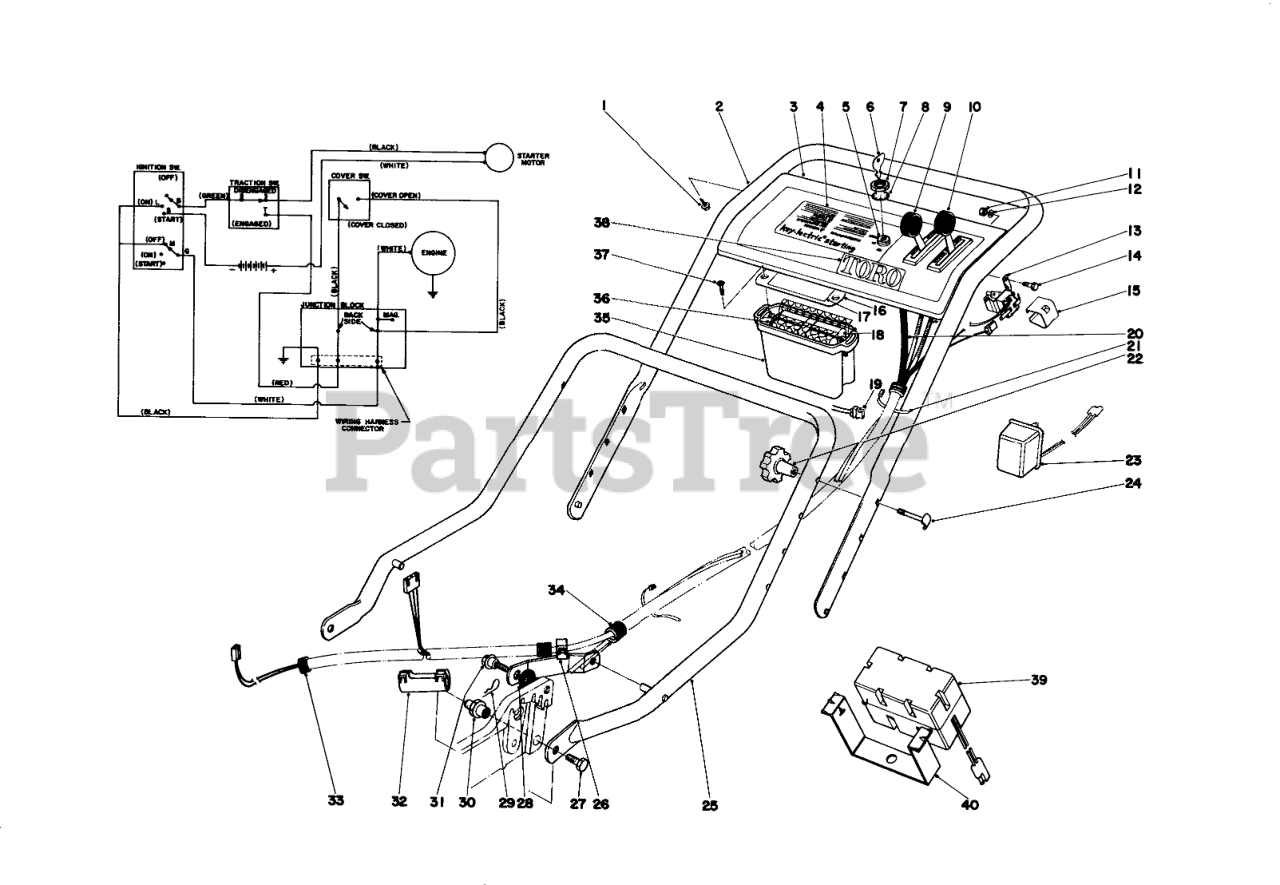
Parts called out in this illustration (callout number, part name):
1	SCREW-HWHTF
2	Upper Handle
3	Control Plate
4	Decal Control Plate
5	SWITCH-STARTER
6	Key
7	NUT-HH
8	WASHER-TOOTH, INTERNAL
9	Control-Throttle
10	Control-Traction
11	NUT-HEX
12	WASHER-FLAT
13	CONTROL SWITCH
14	SCREW-HH
15	Cover Switch
16	Cover
17	Decal Battery
18	Battery Pack Assembly (Incl. Ref. 16-19 & 35-37)
19	Plug & Wire
20	Wiring Harness
21	TIE-CABLE
23	Charger
23	Battery Charger (Used w/item No. 39)
24	HANDLE SCREW
25	Lower Handle
26	RING FITTING
27	SCREW-HH
28	SPACER
29	PIN-COTTER, HAIR
30	HANDLE PIVOT NUT
31	SCREW-SHOULDER
32	Breakout Fitting
33	WIRING HARNESS COVER
34	Upper Wiring Harness
35	Container Pack
36	Spacer
38	TORO LOGO DECAL
39	Battery Gates
40	Battery Adapter
